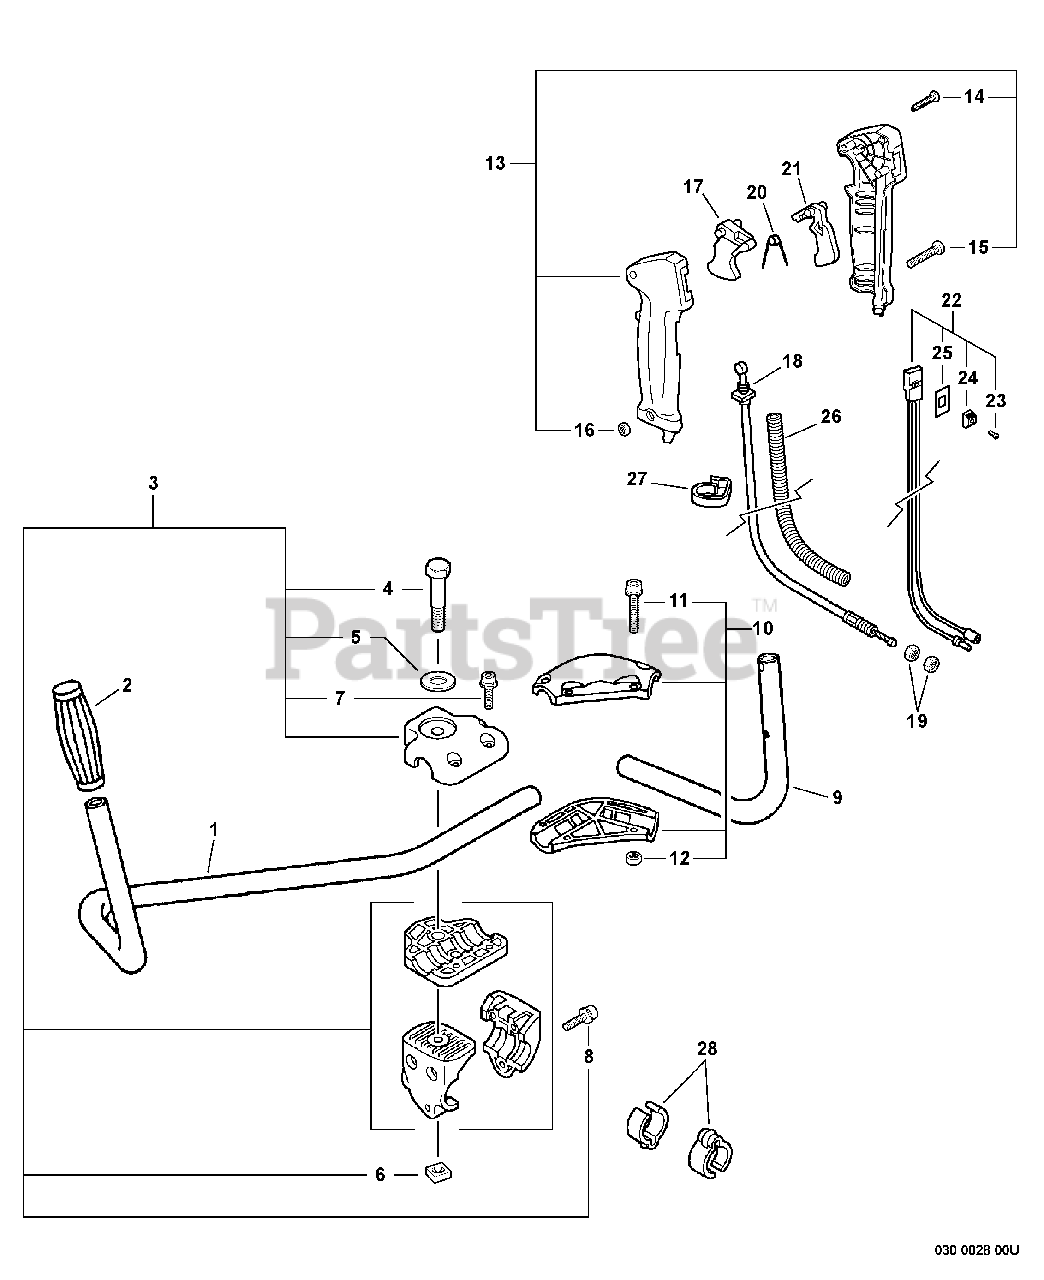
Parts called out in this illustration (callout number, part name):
1	HANDLE, FRONT - LEFT
2	GRIP, HANDLE
3	HANDLE BRACKET KIT
4	BOLT - 8X55
5	WASHER - 8
7	SCREW - 5X20
8	SCREW - 5X30
9	HANDLE, FRONT - RIGHT
10	HANDLE BRACKET KIT
11	SCREW - 5X20
13	THROTTLE CONTROL ASSY
14	SCREW - 3X25
15	SCREW - 5X30
17	TRIGGER, THROTTLE
18	CABLE, THROTTLE
20	SPRING, LOCKOUT LEVER
21	LOCKOUT, THROTTLE
22	IGNITION SWITCH ASSY
23	SCREW - 3X10
24	KNOB, SWITCH - ORANGE
25	COVER, SWITCH - STOP
